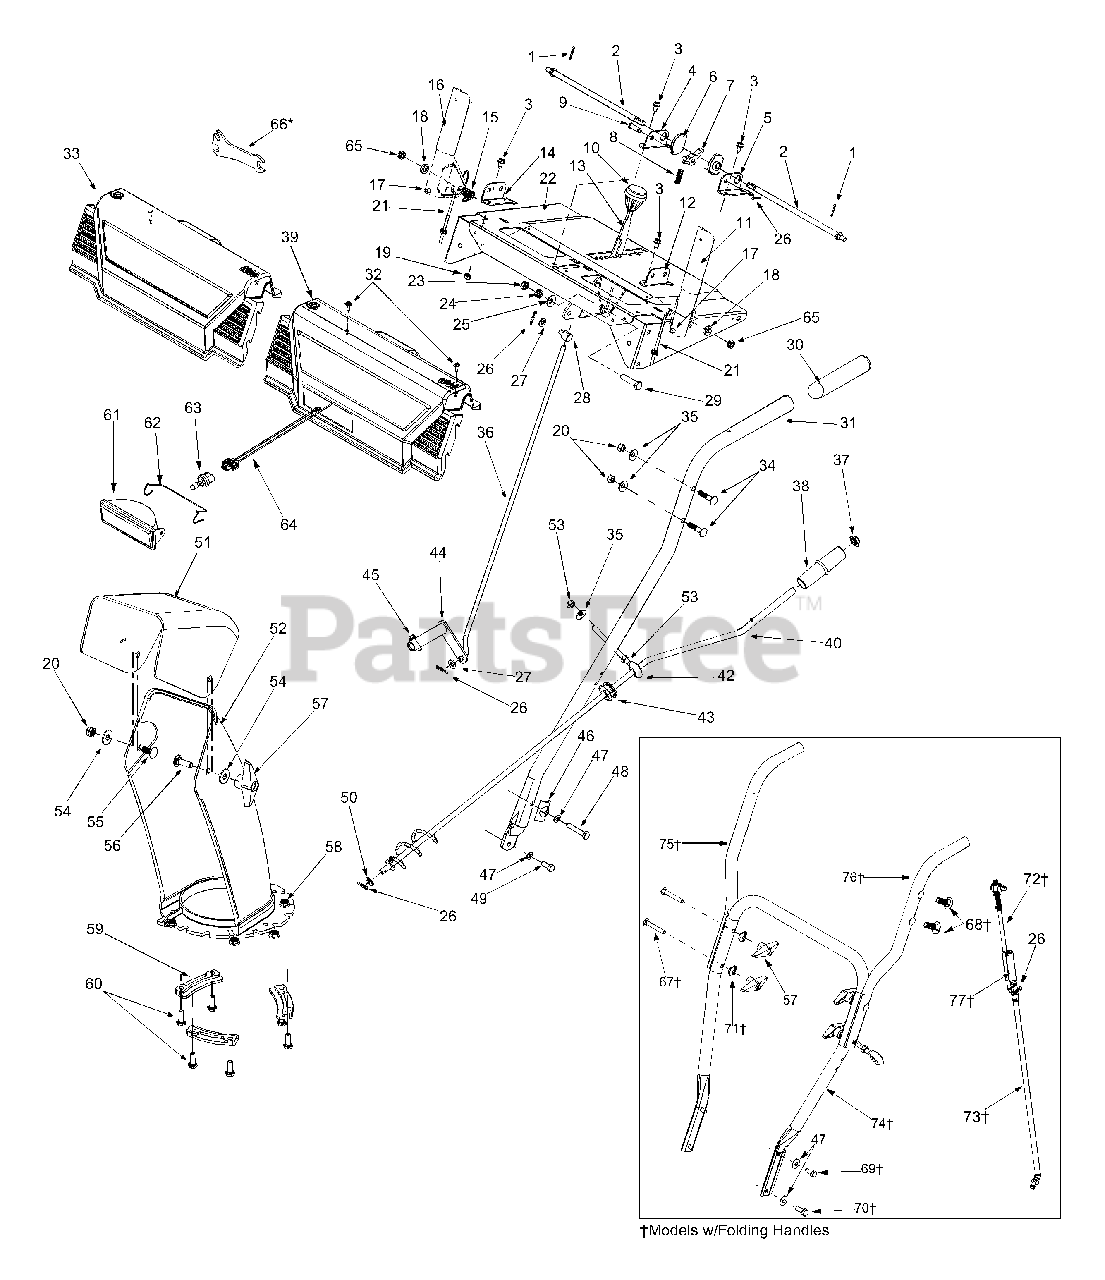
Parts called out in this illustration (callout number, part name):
1	Cotter Pin
3	Hex Washer Screw 1/4-20 x.5
6	Cam Lock Handle
7	Handle Lock Pawl
8	Compression Spring
9	Clevis Pin
10	Shift Knob - Black
11	Handle Assy - LH - Black
15	Torsion Spring
16	Handle Assy - RH - Black
17	Rubber Bumper
18	Washer
19	Hex Nut 1/4-20
20	Hex Nut 5/16-18
21	Z Cable Fitting
24	Compression Spring
25	Bell Washer
26	Cotter Pin
27	Flat Washer 5/16
28	Ferrule
29	Hex Cap Screw 3/8-24 x 1.50
33	Handle Panel (w/o lamp cut-out)
34	Carriage Bolt 5/16-18 x 1.50
35	Bell Washer.340 ID x.872 OD
36	Shift Rod
37	Push Cap
38	Chute Knob - Black
39	Panel (w/ lamp cut-out)
40	Chute Crank
42	Chute Crank Eyebolt
43	Rubber Grommet
45	Hex Washer Screw 1/4-20 x 1.0
46	Handle Tab
47	Lock Washer 5/16
48	H ex Cap Screw 5/16-18 x 2
49	Hex Cap Screw 5/16-18 x.75
50	Flat Washer
51	Upper Chute
52	Lower Chute
53	Hex Nut 5/16-18
54	5/16 Washer
55	Carriage Bolt 5/16-18 x.75
56	Carriage Screw 5/16-18 x 1.0
57	Knob - Black
58	Hex Lock Nut 1/4-20
59	Flange Keeper
60	Hex Cap Screw 1/4-20 x.75
61	Lens Housing Assembly
62	Headlight Retaining Wire
63	Halogen Light
64	Light Harness
65	Hex Lock Nut 5/16-18
66	Wrench
67	Carriage Screw 5/16-18
68	Carriage Bolt 5/16-18 x 1.75
69	H ex Cap Screw 5/16-18
70	H ex Cap Screw 5/16-18 x.75
71	Saddle Washer
72	Upper Shift Rod
73	Lower Shift Rod
